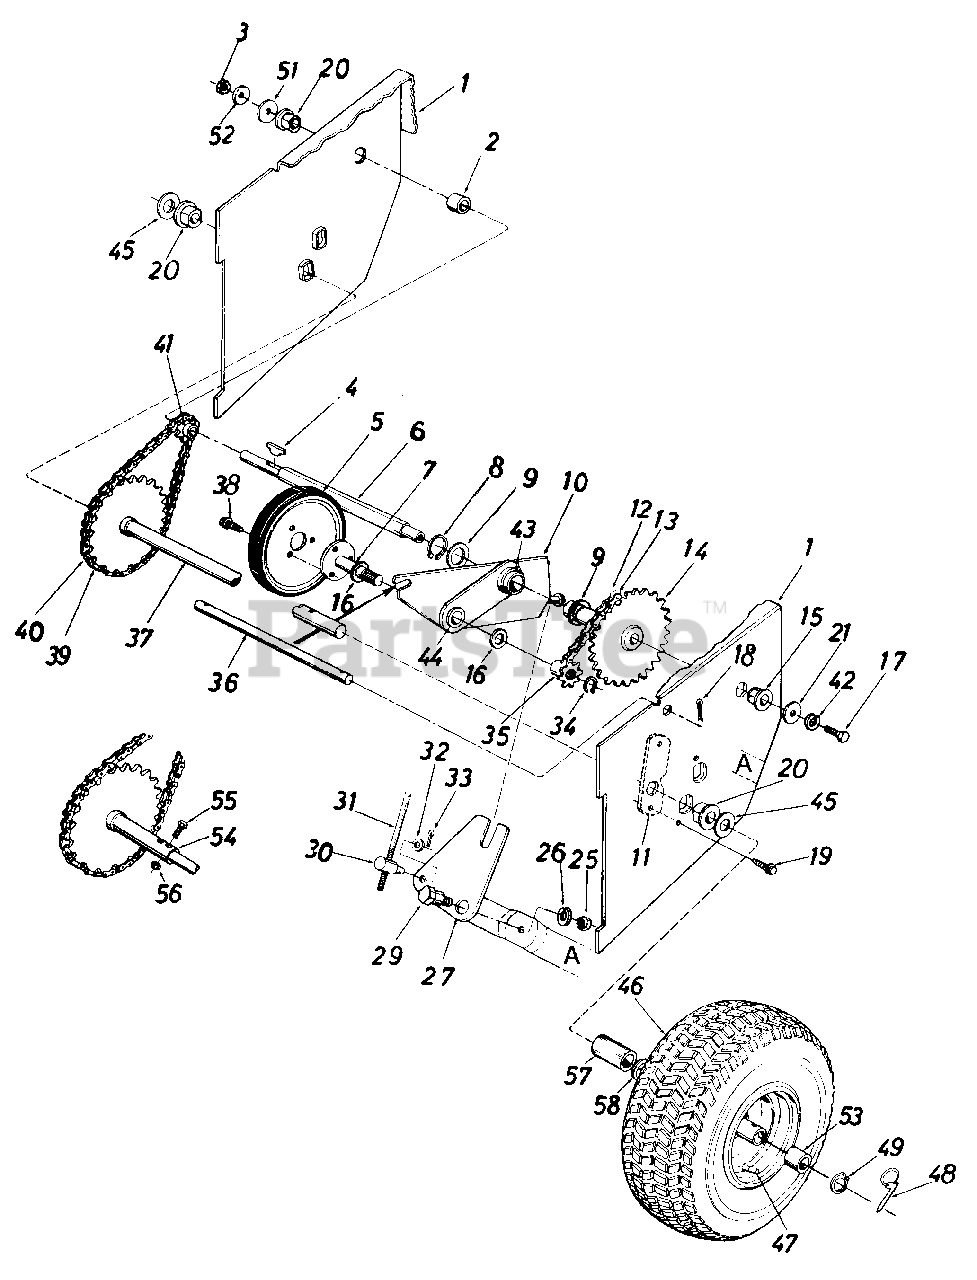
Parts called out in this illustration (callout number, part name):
1	Frame Ass'y.
2	Spacer .50" I.D. x .75" O.D. x.78" Lg.
3	Hex Ins. L-Nut 1/2-20 Thd.
4	#4 Hi-Pro Key 3/32 x 518" Dia.
5	Friction Wheel Ass'y.
6	Hex Shaft
7	Friction Wheel Mounting Plate Ass'y
8	Snap Ring 1.00" Dia. Shaft
9	Fl-Wash. 1.00" x 1.63" O.D. x .03
10	Sliding Bracket Ass'y.
11	Axle Plate 1.75" x 3116"
12	#41 Chain 1/2" Pitch x 35 Links
13	Master Link for #41 Chain
14	32 Teeth Sprocket Ass'y.
15	Hex Flange Brg. .630" I.D.
16	Fl-Wash. .62" I.D. x 1.00" O.D. x .06
17	Hex Lock Bolt 5/16-18 x .62" Lg.
18	Cotter Pin 3/32" Dia. x .75" Lg.
19	Hex Self-Tap Scr. 5/16-24 x .5" Lg.
20	Hex Flange Brg. .751" I.D.
21	Fl-Wash. .34" I.D. x 1.12" O.D. x .125
25	Hex Jam Nut 3/8-16 Thd.
26	L-Wash. 3/8" I.D.
27	Shifting Linkage Bracket
29	Shld. Bolt .625" Dia. x .170" Lg.
30	Adjustment Ferrule
31	Shifting Rod 5/16" Dia. x 32.50" Lg.
32	Fl-Wash. .34" I.D. x .64" O.D. x .06
33	Cotter Pin 3/32" Dia. x .75" Lg.
34	Snap Ring .562" Dia. Shaft
35	Sprocket 7 Teeth x .50" Pitch
36	Shaft .50" Dia. x 9.50" Lg.
37	32 Teeth Wheel Axle Ass'y.
38	Hex Wash. Hd. Self-Tap Scr. 5/16-24 x .50" Lg.
39	#420 Chain 1/2" Pitch x 35 Links
40	Master Link for #420 Chain
41	8 Teeth Center Sprocket
42	L-Wash. 5/16" I.D.
43	Bearing
44	Bronze Bearing
45	Fl-Wash. .76" I.D. x 1.49 O.D.
46	Wheel Assembly
47	Air Valve
48	Klick Pin
49	Snap Ring .75 Dia.
51	Fl-Wash. .53 I.D. x 1.25 O.D. x .10
52	Bell-Wash. .50 I.D. x 1.0 O.D. x .075
53	Sleeve Brg.
54	30 Teeth Sprocket Hub Ass'y.
55	Hex Bolt 1/4-28 x 1.5"
56	Hex L-Nut 1/4-28 Thd.
57	Spacer .75" I.D.
58	Fl-Wash. .793" I.D.
